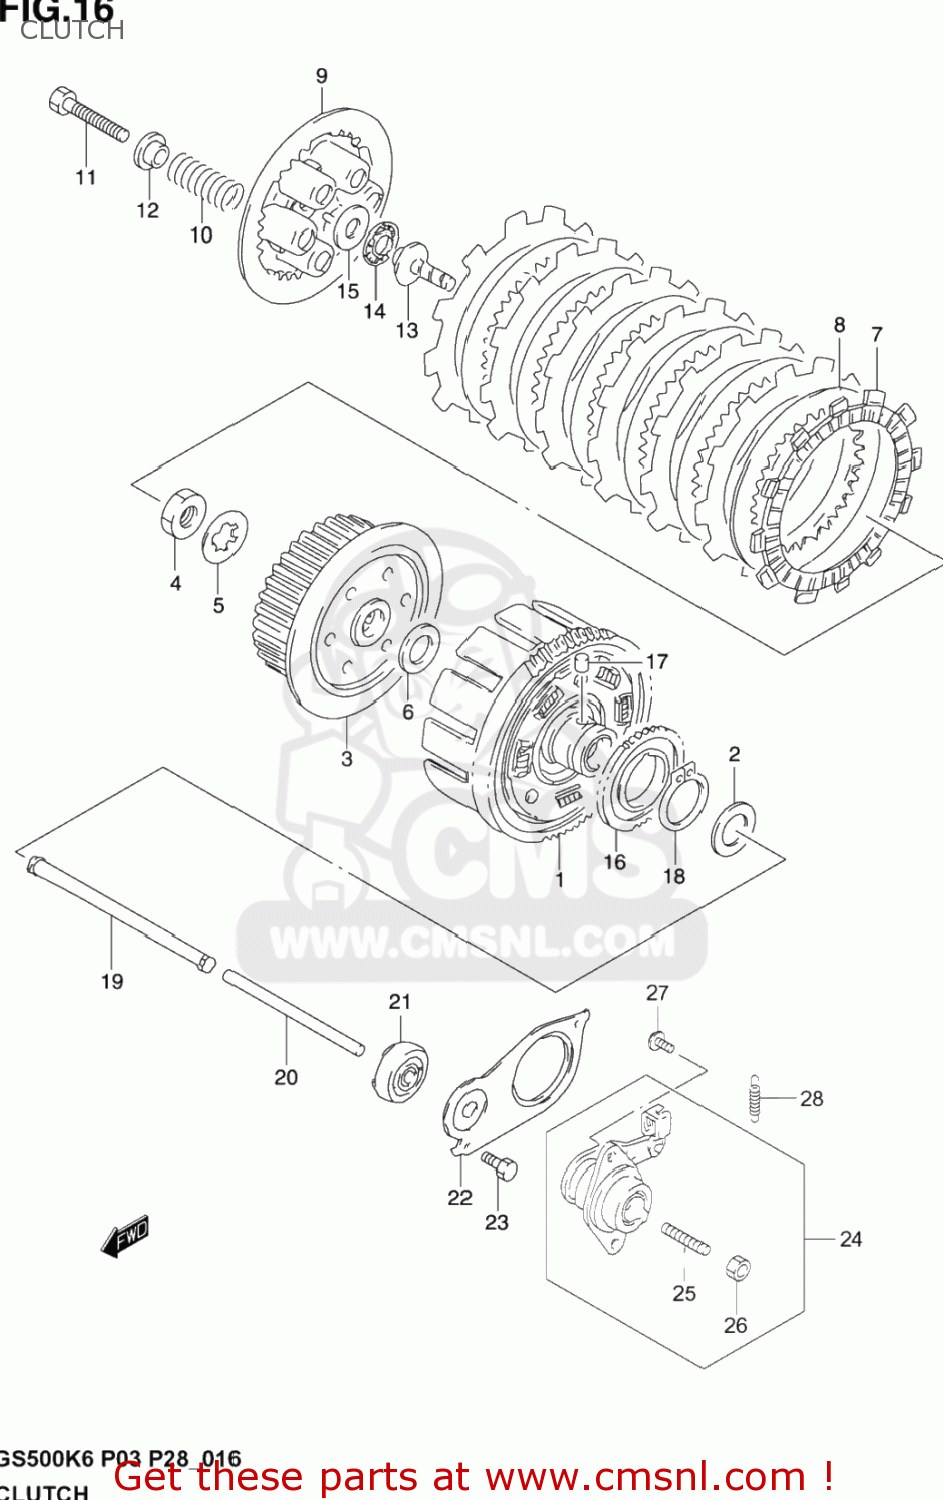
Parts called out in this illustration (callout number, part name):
1	GEAR ASSY,PRI DRIVEN
2	SHIM(25X38X1)
3	HUB,CLUTCH SLEEVE
4	NUT
5	WASHER,LOCK
6	WASHER(20X44X3)
7	PLATE,CLUTCH DRIVE (NAS)
8	PLATE,CLUTCH DRIVEN(T:1.6) (NAS)
9	DISC,CLUTCH PRESSURE
10	SPRING
11	BOLT(6X40)
12	SPACER,CLUTCH SLEEVE HUB
13	PIECE,CLUTCH PUSH
14	BEARING(15X28X2)
15	WASHER(15.5X28X1)
16	GEAR,OIL PUMP DRIVE(NT:39)
17	PIN(6X6)
18	CIRCLIP
19	ROD,PUSH,R
20	ROD,CLUTCH PUSH,L
21	SEAL,OIL(6X34X10)
22	RETAINER,PUSH ROD OIL SEAL
23	BOLT
24	SCREW ASSY,CLUTCH RELEASE
25	SCREW(6X25)
26	NUT
27	SCREW 6X16
28	SPRING
